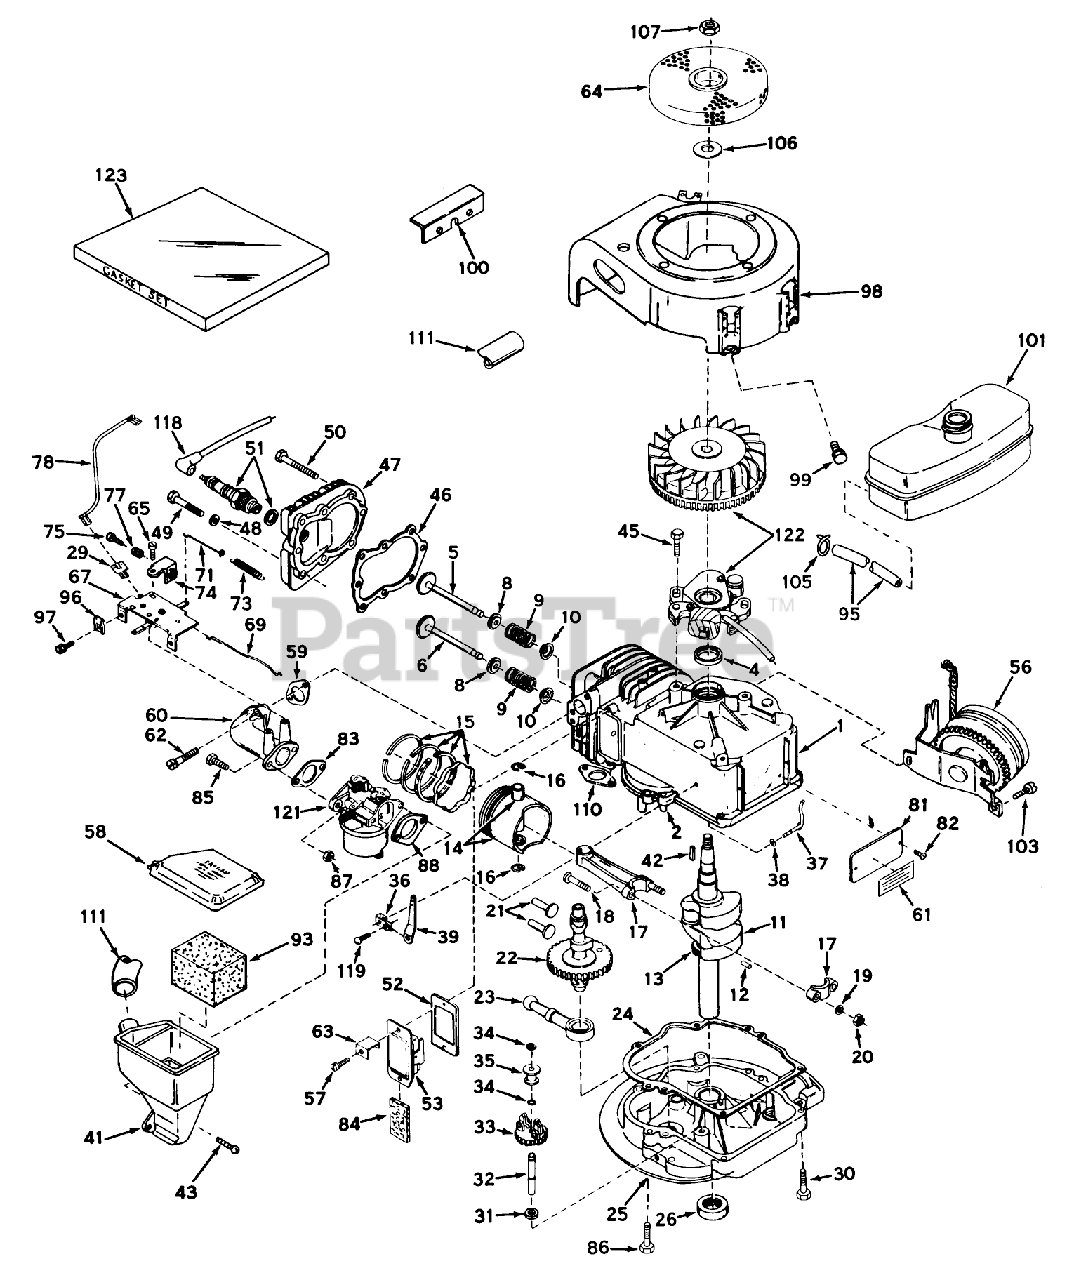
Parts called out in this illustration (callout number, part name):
1	Cylinder Assy. (Incl. Ref. 2 4)
2	Pin-Dowel
4	OIL SEAL
5	Valve, Intake (Incl. Ref. #38, 39 40) (Std.)
5	Valve, Intake(1/32"overs.)(Incl. Ref. 8, 9 10)
6	Valve, Exhaust (Standard)(Incl. Ref. 8, 9 10)
6	Valve, Exhaust (1/32" Overs.(Incl. Ref. 8, 9 10)
8	Cap-Upper Valve Spring
9	Spring-Valve
10	Cap-Valve, Spring
11	Crankshaft Assy. (Incl. Ref. 12 13)(Model LAV35-40455H)
12	Pin, Groove
13	Gear, Crankshaft
14	Piston Pin Assy. (Incl. 2 of No. 16)(Standard)
14	Piston Pin Assy. (Incl. 2 of No. 16)(.010 oversize)
14	53020 ADN. TO 28594
15	Piston Ring Set Std.
15	Piston Ring Set .010 O.S.
15	Piston Ring Set .020 O.S.
16	Ring-Retaining, Piston Pin
17	Rod Assy., Connecting (Incl. Ref. #17)
18	Bolt, Connecting
19	Washer
20	LOCKNUT
21	Lifter-Valve
22	Camshaft
23	Oil Pump ASM
24	Gasket, Mounting
25	Flange Assy., Mounting (Incl. #26 32)
26	Seal Oil
29	Terminal
30	Screw (1/4-20 x 1-1/4)
31	Washer-Flat
32	Shaft-Governor
33	Governor Gear ASM
34	Ring-Retaining
35	Spool-Governor
36	Clamp-Lever, Governor
37	Rod, Governor (Incl. No. 36)
38	Washer-Flat
39	Governor Lever
41	Body, Air Cleaner
42	Key Flywheel
43	Screw, Fil. Hd. Sems
45	Screw
46	Gasket-Cylinder Head
47	CYLINDER HEAD
48	Washer
49	Screw
50	Screw Hex Hd. Cap
51	SPARK PLUG
52	Gasket Breather
53	Breather Assembly (Incl. Nos. 52 84)
56	Starter, Side Mount
57	Screw
58	Cover, Air Cleaner
59	Gasket, Intake
60	Pipe, Intake
61	480B GIL SNWTHWR O/
62	Screw, Fil. Hd. Sems
63	Retainer Clip
64	Screen, Flywheel
65	Screw (10-24 x 9/16)
67	Control Assy., Speed
69	Link Governor
71	Link-Governor
73	Spring, Governor
74	Brachet, Control
75	Screw, Hex Hd.
77	Spring
78	Wire, Ground
81	IDENTIFICATION PLATE
82	Stud
83	Gasket
84	Element-Breather
86	Screw
87	Nut and Lock Washer (1/4-28)
88	Gasket-Air Cleaner
93	Element, Air Cleaner
95	Line-Fuel (8.62)
96	Conduit
97	Screw (10-32 x 3/8)
98	Housing, Blower
99	Screw (1/4-20x19/32)
100	Bracket, Shroud
100	** Bracket, Shroud
101	Tank, Fuel
103	Screw
105	Clamp-Line, Fuel
106	Washer
107	Hex Nut
110	Gasket Exhaust
111	Tube, Air Cleaner
118	Cover-Spark Plug
119	Screw
121	Carburetor
122	Magneto
123	Gasket Set (Incl. Items Marked *)
